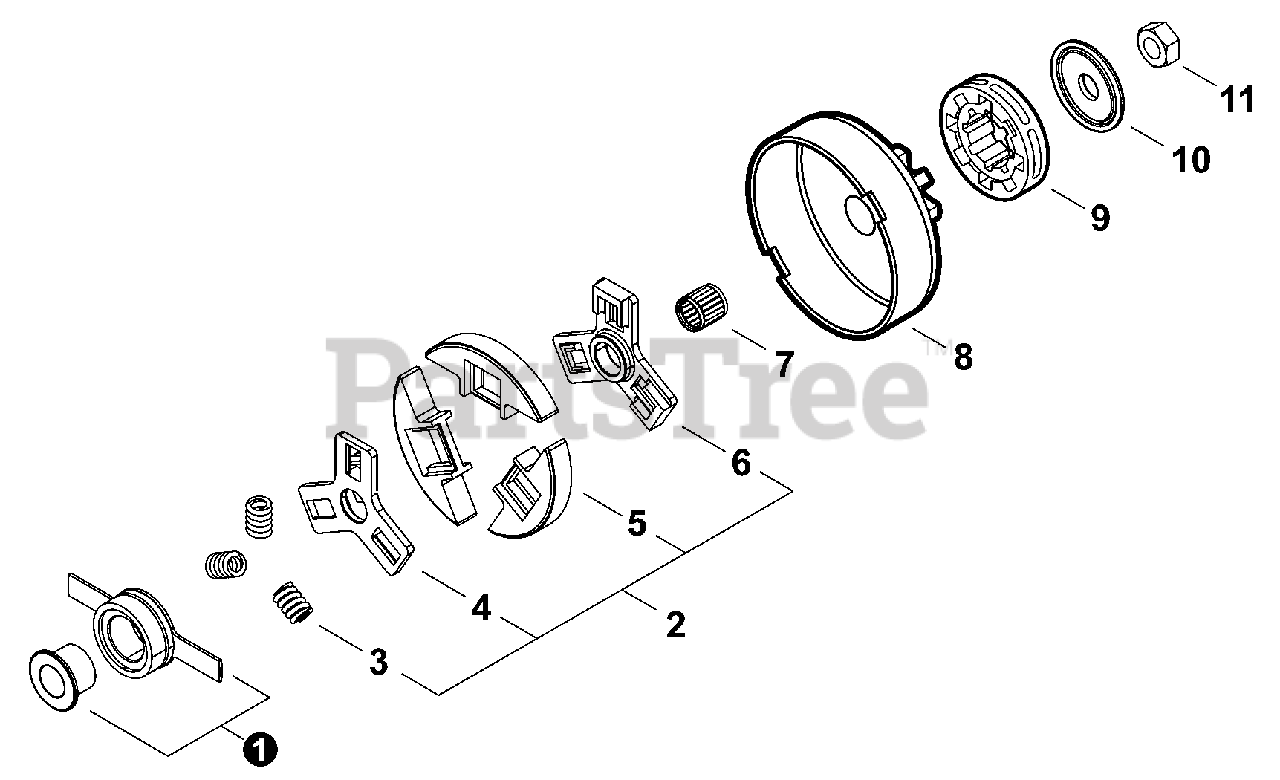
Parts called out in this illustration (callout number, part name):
1	GEAR ASSY, WORM
2	CLUTCH ASSY
3	SPRING, CLUTCH
4	BOSS, CLUTCH A
5	SHOE SET, CLUTCH (3PCS)
6	BOSS, CLUTCH B
7	BEARING, NEEDLE 10
8	DRUM, CLUTCH
9	SPROCKET, .325 RIM
10	WASHER 10
